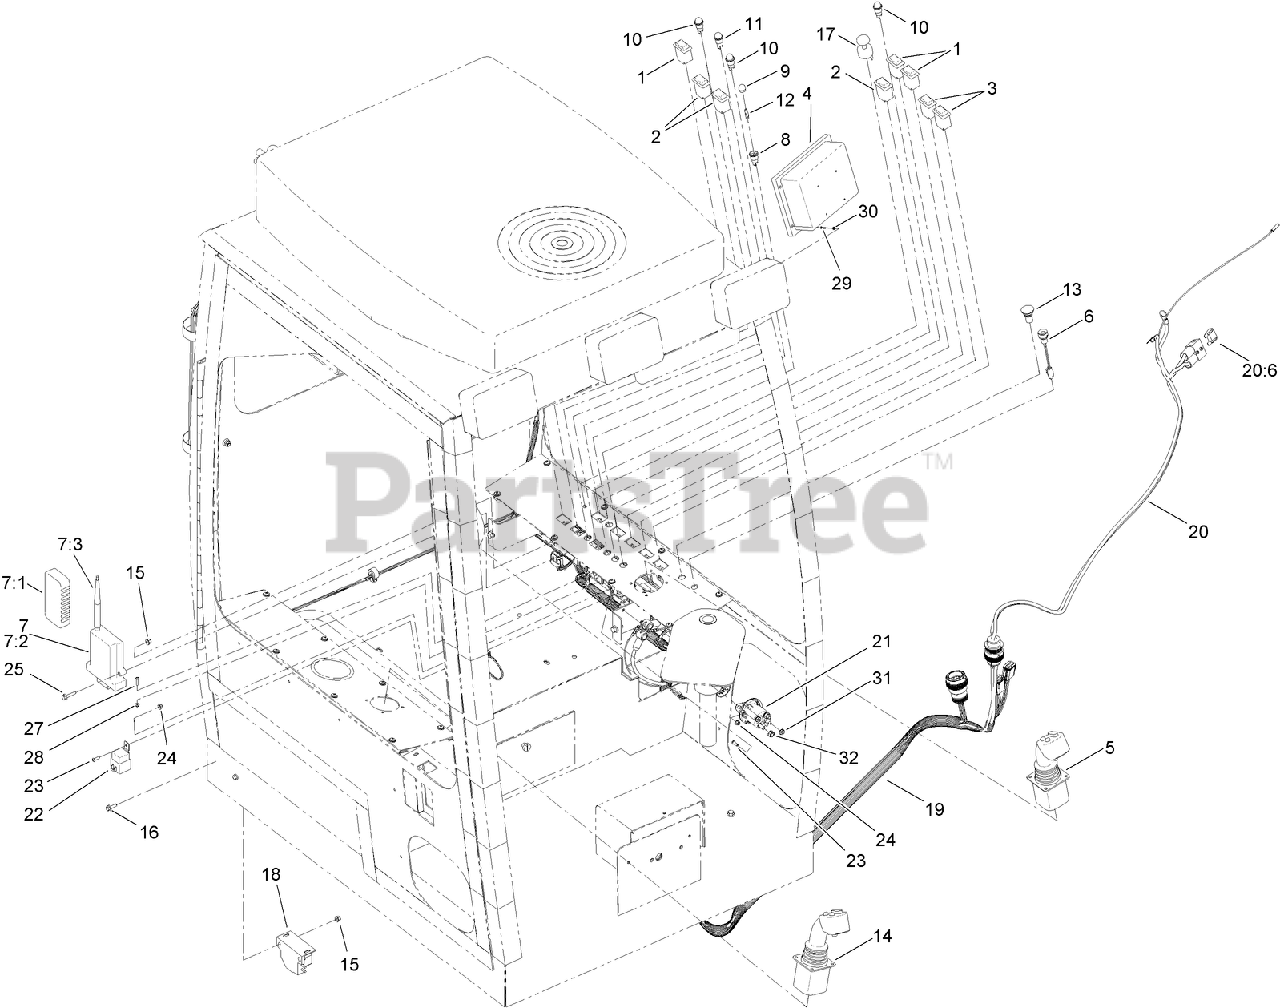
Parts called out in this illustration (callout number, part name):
1	SWITCH-ROCKER, 2 POLE (ON/OFF)
2	SWITCH-ROCKER, 2 POLE
3	SWITCH-ROCKER, 1 POLE (ON)OFF/ON(OFF)
4	DISPLAY-DP600, UNPROGRAMMED
5	JOYSTICK-MODIFIED (LEFT HAND)
6	SWITCH-START, GREEN BUTTON
7	LONG RANGE EXIT SIDE LOCKOUT KIT
7:1	HANDHELD-LOCKOUT
7:2	BASE UNIT-LOCKOUT
7:3	ANTENNA-LOCKOUT
8	TYPE T-2 SOCKET ASM
9	LENS-DOME, FLUTED RED (TYPE T-2)
10	LENS-DOME, FLUTED GREEN (TYPE T2)
11	LENS-DOME, FLUTED AMBER (TYPE T2)
12	LAMP-LED
13	BUTTON-PUSH, RED MUSHROOM
14	JOYSTICK-CARRIAGE
15	NUT-FLANGE, NI
16	SCREW-HHF
17	SWITCH-WIPER
18	ALARM-BACKUP
19	HARNESS-WIRE, CAB
20	HARNESS-WIRE, CAB POWER
20:6	FUSE-MAXI, 60 AMP
21	SOLENOID
22	RELAY
23	SCREW-HSBH
24	NUT-HF
25	SCREW-HHF
27	SCREW-HSBH
28	NUT-HHF
29	SCREW-PRH, SLOTTED
30	NUT-LOCK, NI
31	NUT-KEPS
32	NUT-KEPS
